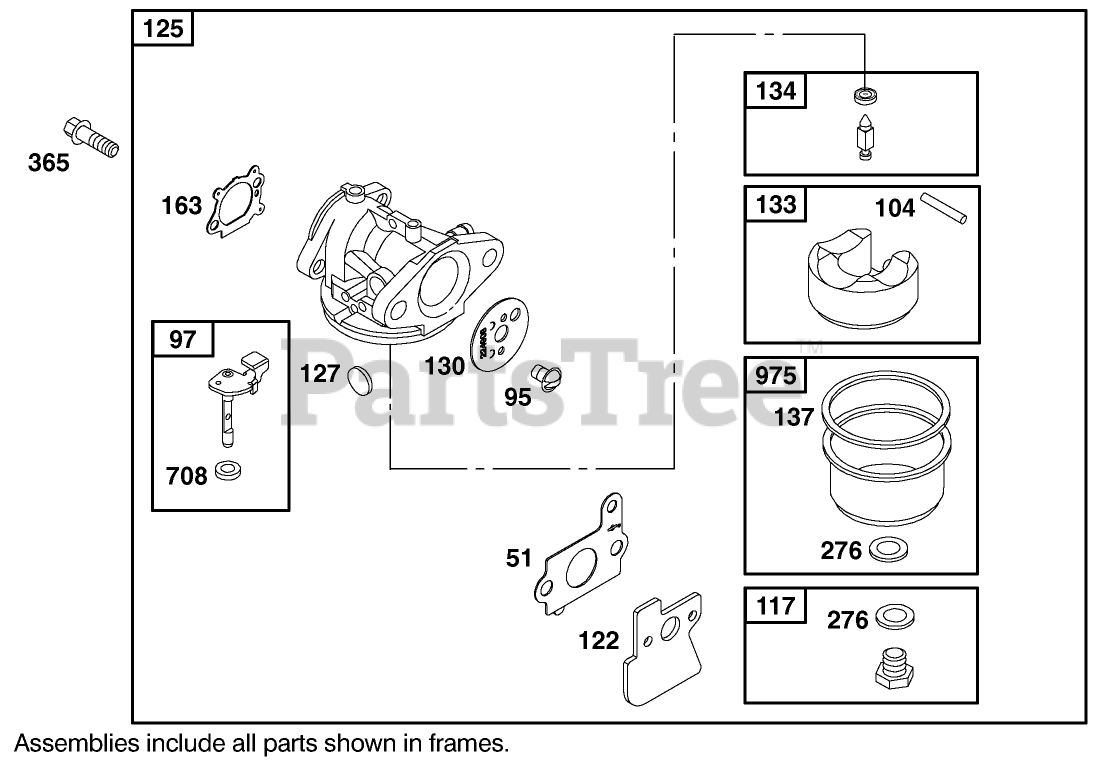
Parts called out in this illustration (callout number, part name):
51	Gasket-Intake
95	Valve-Choke
97	Shaft?Throttle
104	Pin-Hinge, Float
117	Jet-Main
122	Gasket-Intake
125	Carburetor
127	Welch Plug (Sold in Kit Only)
130	Valve?Throttle
133	Float-Carburetor
134	Valve-Inlet (Includes Seat)
137	Float Bowl Gasket (Sold in Kit Only)
163	Air Cleaner Gasket
276	Bowl Washer (Sold in Kit Only)
365	Screw
708	Seal-Shaft, Choke Throttle
975	Bowl-Float
